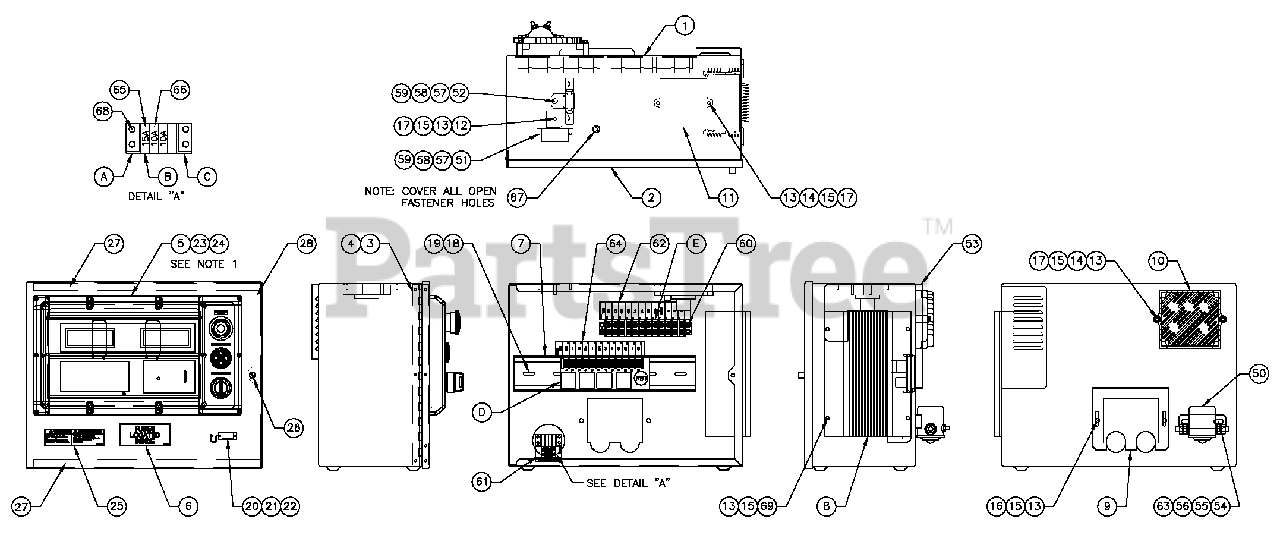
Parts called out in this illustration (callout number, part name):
1	ENCLH/G CONTROL PANEL
2	COVER CONTROL PANEL
3	HINGECONTINUOUSH PANEL
4	RIVET POP .125X .275SS
5	ASSYPROGRAMMEDH-100
6	DECAL FUSES LOCATED INSIDE
7	RAILSNAPTRACK PCB HOLDER BULK
8	ASSYPCB 10A UL BATT CHRGR12V
9	PLATE HARNESS CLAMP
10	ASSYPCB PWR AVR W/AMP HEADER
11	ASSY PCB BOSCH GOV DRIVER
12	DIO BRIDGE25A 600V
13	WASHER LOCK M5
14	SCREW PPHM M5-0.8X 30SS
15	WASHER FLAT M5
16	SCREW HHPM M5-0.8 X 12
17	NUT HEXM5-0.8 G8 YEL CHR
18	WASHER FLAT M4
19	SCREW PHTT M4-0.7X 10ZYC
20	CONN DUST CAP W/CHAIN DB9
21	WASHER FLAT M3.5
22	SCREW PHTT M3.5-0.6 X 10
23	SCREW PPHM M4-0.7X 8 BLXOX
24	WASHER LOCK #8-M4
25	DECAL WRN BATT CHRG12/24V BI
26	M5-0.8 CAPTIVE PANEL KNLD HD
27	SEAL COVER 3.18 X 12.7X 382
28	SEAL COVER 3.18 X 12.7X 283
50	RELAY CONTACTOR 12VDC
53	COVER CONTROL PANEL SIDE
54	SCREW HHC 1/4-20X 3/4G5
55	WASHER FLAT M6-1/4
56	WASHER LOCK M6-1/4
57	WASHER LOCK M3
58	NUT HEXM3-0.5 G8 YEL CHR
59	WASHER FLAT M3
60	SCREW PHTT#6-32X 5/8ZYC
61	DECAL CPL CONTROL PANEL FUSES
62	DECAL CPL 5.4/6.8LTB3
63	NUT HEX 1/4-20 STEEL
64	DECAL CPL 5.4/6.8L RELAY BOARD
65	FUSE ATO TYPE 15 AMP (BLUE)
66	FUSE ATO TYPE 10 AMP (RED)
67	SEAL WEATHER.45"DIA
68	SCREW PHTT#6-32X 3/8ZYC
69	SCREW PHTT M5-0.8X 16ZYC
A	ADPTR RH SIDE WICKMANN 178.6191
B	HOLDERFUSE WICKMANN 178.6150
C	ADPTR LH SIDEWICKMANN 178.6192
D	ASSYPCB G-PANEL RELAY 12VDC
E	BLOCK TERM 20A 12X 6 X1100V
